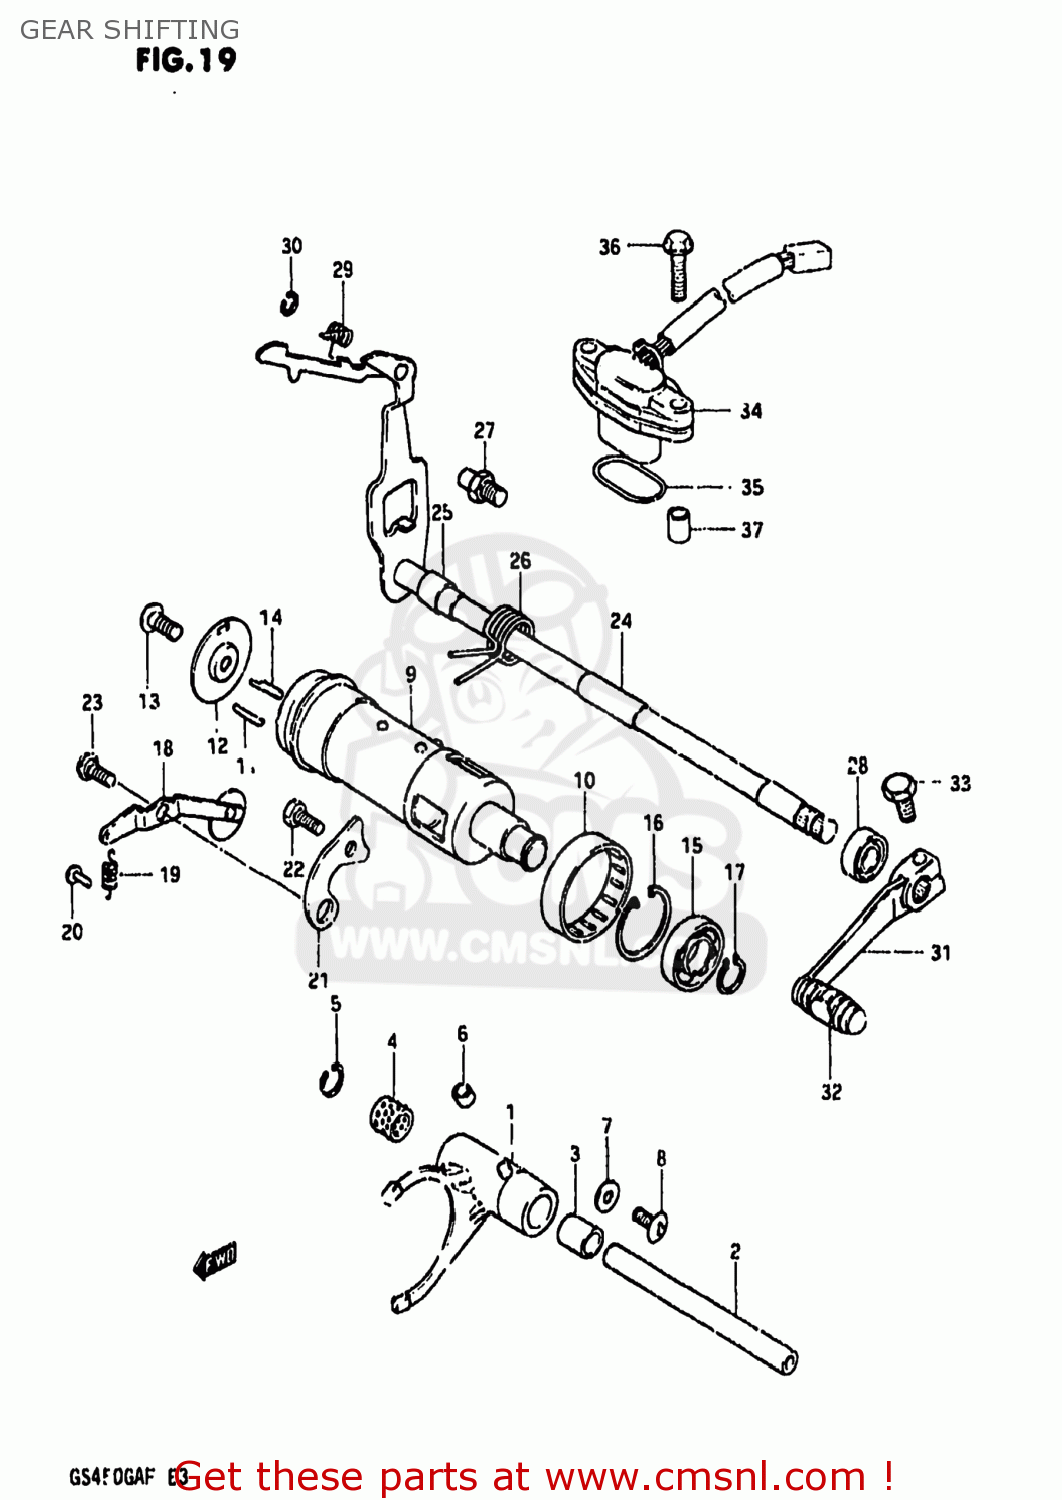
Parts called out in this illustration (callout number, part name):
1	FORK,GEAR SHIFT
2	SHAFT,GEAR SHIFT FORK NO.1
3	SPACER (10X14X17)
4	BEARING
5	CIRCLIP
6	SPACER
7	WASHER
8	SCREW
9	CAM,GEAR SHIFT
10	BEARING(40X47X12)
11	PIN(4X18.5)
12	RETAINER,GEAR SHIFT CAM DR PIN
13	SCREW
14	PIN
15	BALL BEARING
16	CIRCLIP
17	CIRCLIP,15MM
18	STOPPER,GEAR SHIFT CAM NO.1
19	SPRING
20	RIVET
21	GUIDE,GEAR SHIFT CAM
22	BOLT, UPPER
23	BOLT
24	SHAFT,GEAR SHIFT
25	SPACER(12X20X15.3)
26	SPRING
27	STOPPER,GEAR SHIFT CAM
28	OIL SEAL
29	SPRING
30	E RING
31	LEVER ASSEMBLY,GEAR SHIFTING
32	RUBBER,GEAR SHIFT PEDAL
33	BOLT
34	BASE ASSEMBLY,NEUTRAL SWITCH TERMINAL
36	BOLT
37	PIN(6.2X8X11)
